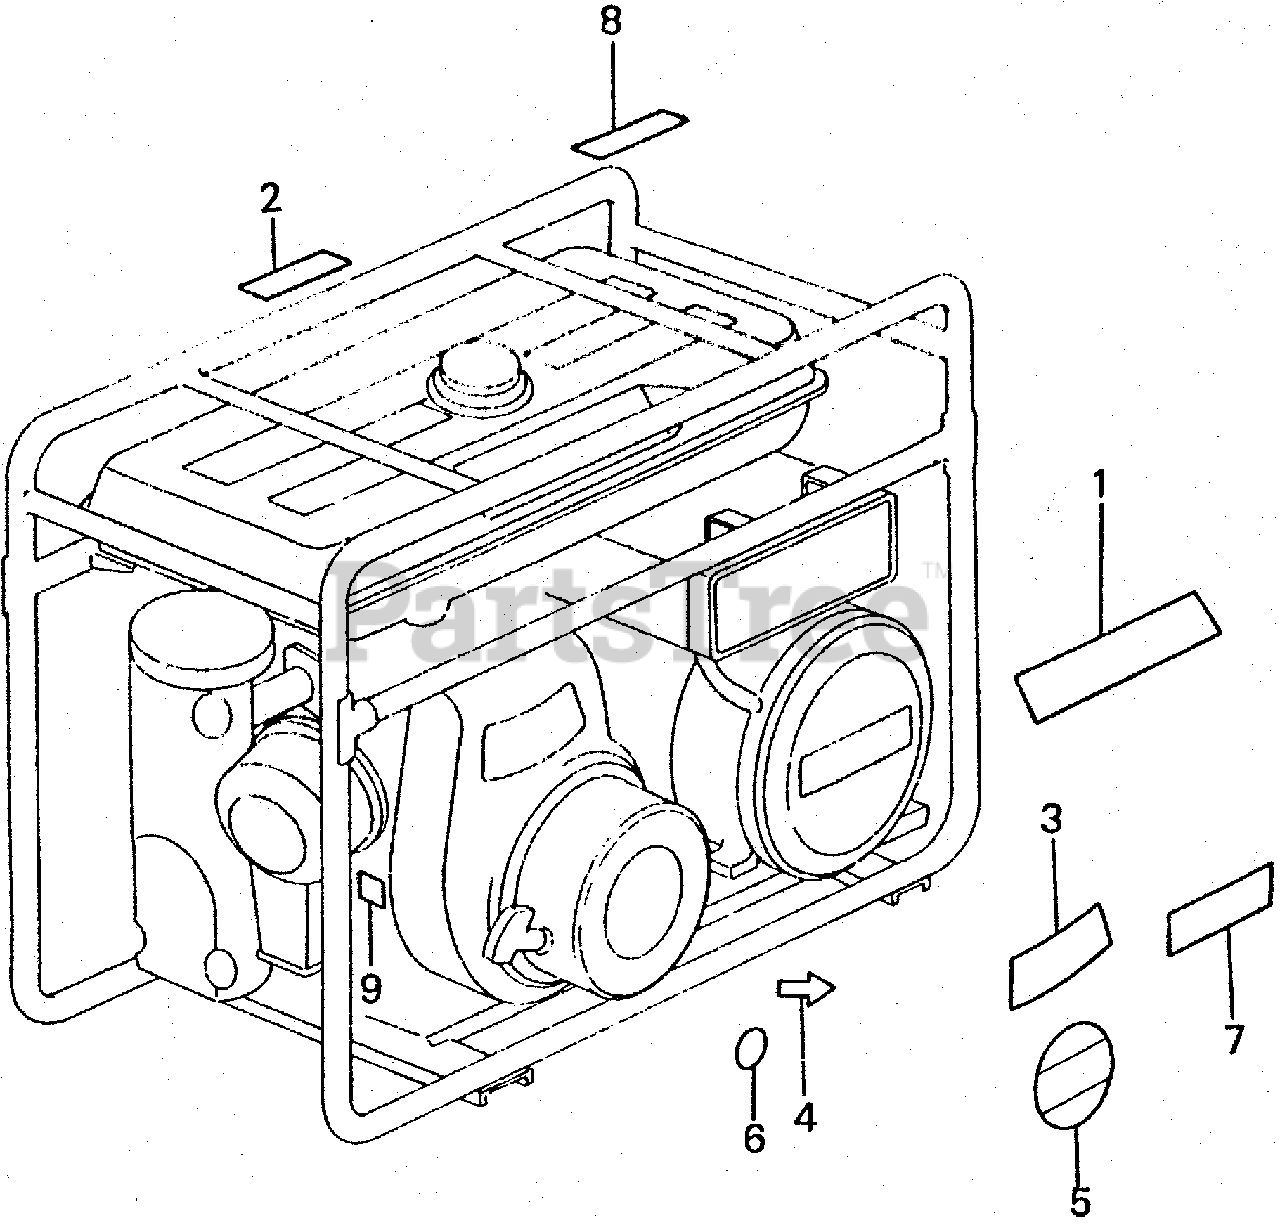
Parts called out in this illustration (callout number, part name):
1	MARK, TOP (NOT AVAILABLE)
2	MARK A, CAUTION
3	PLATE, CAUTION (NOT AVAILABLE)
4	MARK, CHOKE
5	MARK, C.D.I.
6	MARK, KNOB (NOT AVAILABLE)
7	PLATE, DESCRIPTION (NOT AVAILABLE)
8	MARK, CAUTION (ENGLISH/FRENCH/SPANISH)
9	MARK, OIL CAUTION
